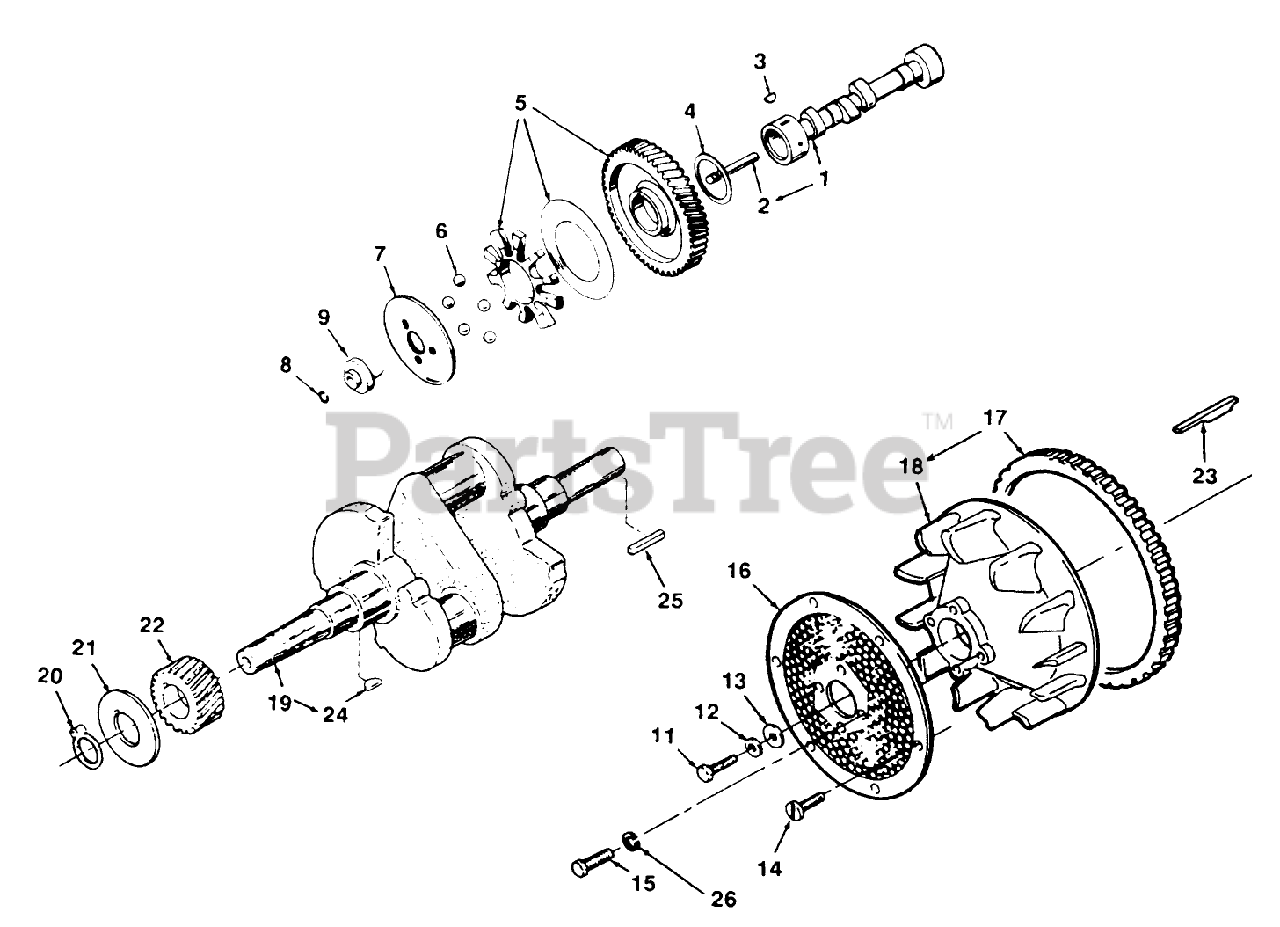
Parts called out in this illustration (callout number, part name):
1	Camshaft (Incl. Center Pin)
2	PIN-CENTER
4	WASHER-THRUST
5	Gear-Camshaft (Incl. Plate & Spacer)
6	BEARING
7	CUP-GOVERNOR
9	HUB-GOVERNOR CUP
11	SCREW
12	WASHER-FLAT
13	WASHER-FLAT
14	LOCK SCREW
15	HX HD LOCK CAPSCREW
16	Screen
18	Flywheel (Incl. Ring-Gear)
19	Crankshaft (Incl. Keys)
21	WASHER
22	GEAR-CRANKSHAFT
23	KEY-FLYWHEEL
25	KEY - WOODRUFF
26	WASHER - LOCK (5/16")
